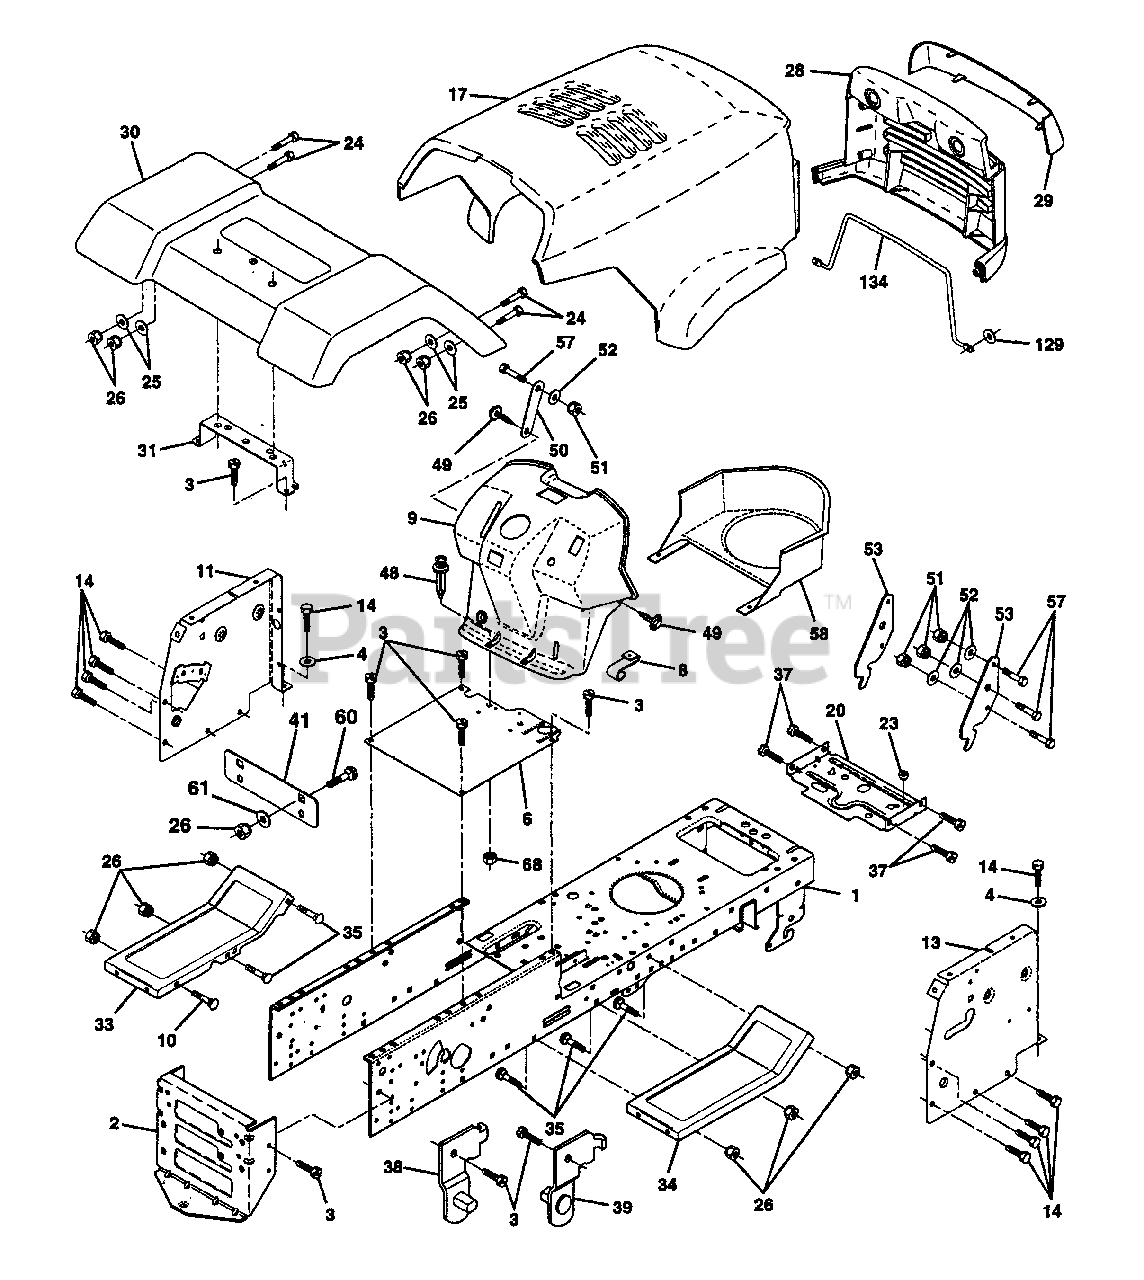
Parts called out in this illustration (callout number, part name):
1	Chassis Weldment 11 ga
2	Drawbar, Stretch
3	Screw Thdrol 3/8-16x3/4 Ty-tt
4	Washer 13/32 x 3/4 x 16 Ga.
6	Saddle LT Fender Shift
8	Clip insulator .406 Mtg Hole
9	Dash Private Label
10	Bolt Carriage 3/8-16 x 1
11	Panel Pnt Dash Lh
12	Clip Tinnerman P/L
13	Panel Dash Rh
14	Screw Thdrol 3/8-16x1/2 Ty-tt
17	Hood Private Label LT Husq
20	Plate Pnt Mtg Btry/FL
24	Bolt Fin Hex 3/8-16unc X 1 Gr. 5
25	Washer 13/32 X 13/16 X 12 Ga
26	Nut Lock Hex W/Ins 3/8-16 UNC
28	Grille Private Label/LT
29	Lens Grille Private Label
30	Fender Pnt
31	Bracket Pnt Support Fender
33	Footrest Pnt Lh
34	Footrest Pnt Rh
35	Bolt Rdhd Sht Sqnk 3/8-16 X3/4
37	Screw Thdrol 5/16-18 X 1/2
38	Bracket, Asm. Pivot, L.H., Mower Rear
39	Bracket, Asm. Pivot, R.H., Mower Rear
40	Spacer Fender Lt
41	Pate Extension Fender Lt
48	Rivet Push Plate D Plastic Blk
49	Screw Hexwsh. Thdrol 1/4-20 x 3/4
51	Nut Lock Hex W/Ins 1/4-20
52	Washer 9/32 x 7/8 x 16 Ga.
53	Bracket Pnt. Pick Off LT/PL Husq
57	Screw Hex 1/4-20 x 3/4
58	Air Duct P/L
60	Bolt Carriage 3/8-16 x 3/4
61	Washer 17/32 x 7/8 x 16 Ga.
129	Washer 9/32 x 5/8 x 16 Ga.
134	Rod Support Hood LT/PL Husq.
